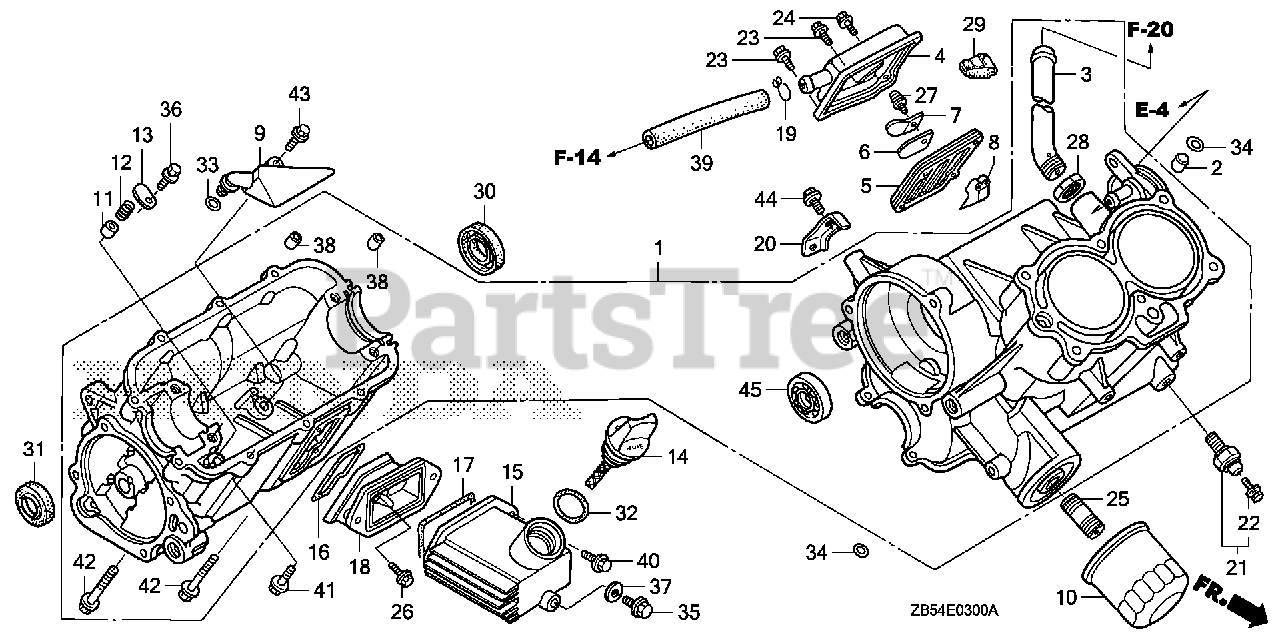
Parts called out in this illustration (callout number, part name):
1	CYLINDER ASSY.
2	ORIFICE, OIL CONTROL
3	PIPE, JOINT
4	COVER, BREATHER
5	PLATE, BREATHER
6	PLATE, VALVE
7	STOPPER, VALVE
8	GUARD, BREATHER
9	FILTER, OIL
10	FILTER, OIL
11	VALVE, CHECK
12	SPRING, VALVE
13	PLATE, VALVE
14	CAP, OIL FILLER
15	RESERVOIR, OIL
16	O-RING, OIL JOINT
17	O-RING, OIL RESERVOIR
18	JOINT, OIL RESERVOIR
19	CLIP, BREATHER TUBE
20	BRACKET, CABLE CLAMP
21	SWITCH, OIL PRESSURE
22	BOLT-WASHER (4X8)
23	BOLT, FLANGE (6X12) (CT200)
24	BOLT, FLANGE (6X14)
25	PIPE, OIL PASSAGE
26	BOLT, FLANGE (6X23)
27	SCREW-WASHER (5X8)
28	NUT, PIVOT LOCK
29	RUBBER, CYLINDER
30	OIL SEAL (33X48X7)
31	OIL SEAL (30X44X7)
32	O-RING (26X2.7)
33	O-RING (11.8X2.4)
34	O-RING (10.8X2.4) (ARAI)
35	BOLT, DRAIN PLUG (12MM)
36	BOLT-WASHER (6X12)
37	WASHER, DRAIN PLUG (12MM)
38	PIN A, DOWEL (10X16)
39	BULK HOSE, VACUUM (12X1000) (12X340)
40	BOLT, FLANGE (6X25)
41	BOLT, FLANGE (6X28)
42	BOLT, FLANGE (8X55)
43	BOLT, FLANGE (6X18)
44	BOLT, FLANGE (8X16) Use from Engine SN 1000016.
45	BEARING, RADIAL BALL (6202)
